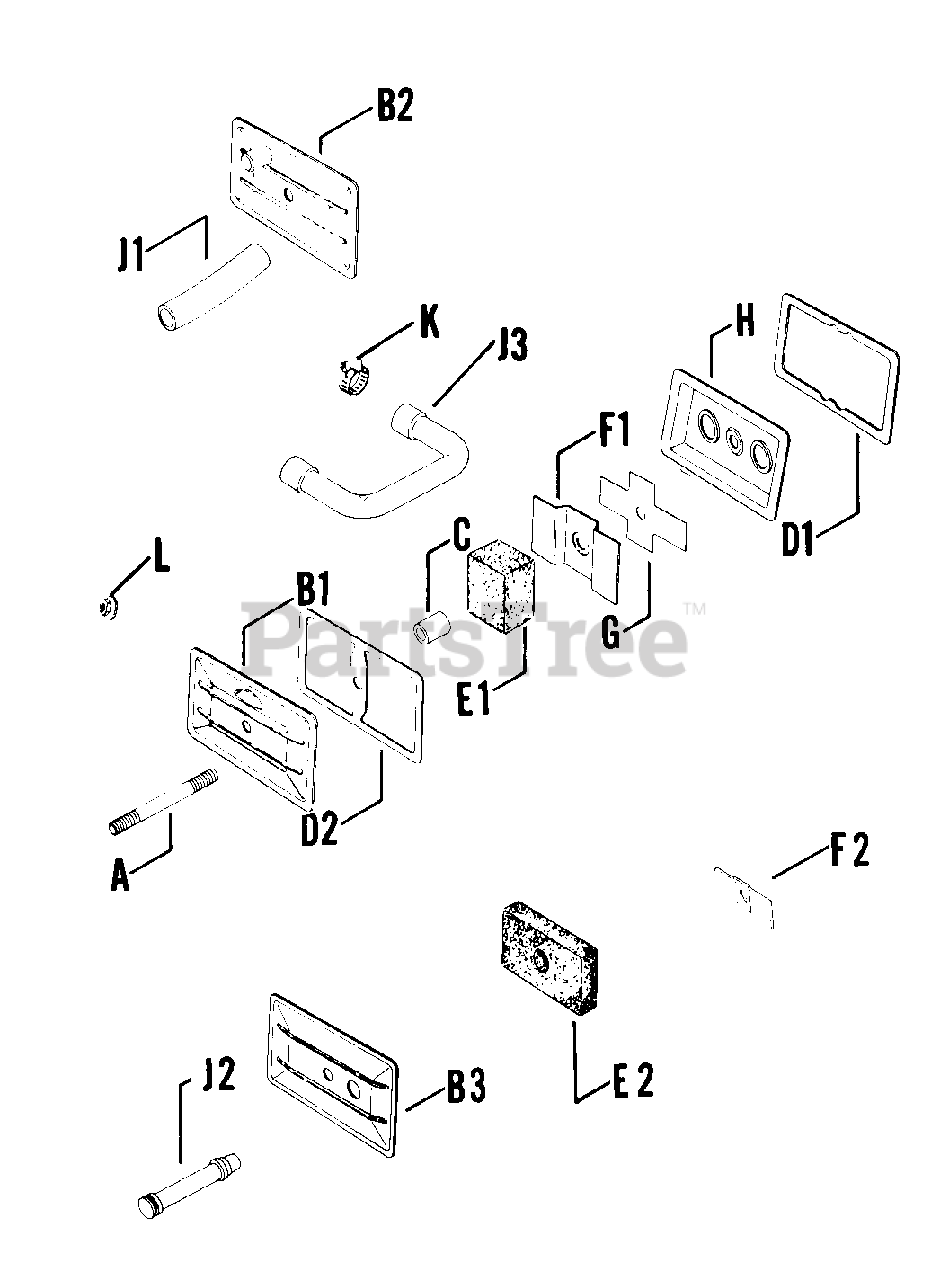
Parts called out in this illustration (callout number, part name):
A	STUD, 1/4-20x3-1/4" - DISCONTINUED
B1	COVER - USE A-235418-S
C	SEAL, BREATHER
D1	GASKET, VALVE COVER
D2	GASKET, VALVE COVER
E1	FILTER, BREATHER
F1	BAFFLE, BREATHER
G	REED, BREATHER - Use 47 402 01-S Breather Reed
H	PLATE, BREATHER
